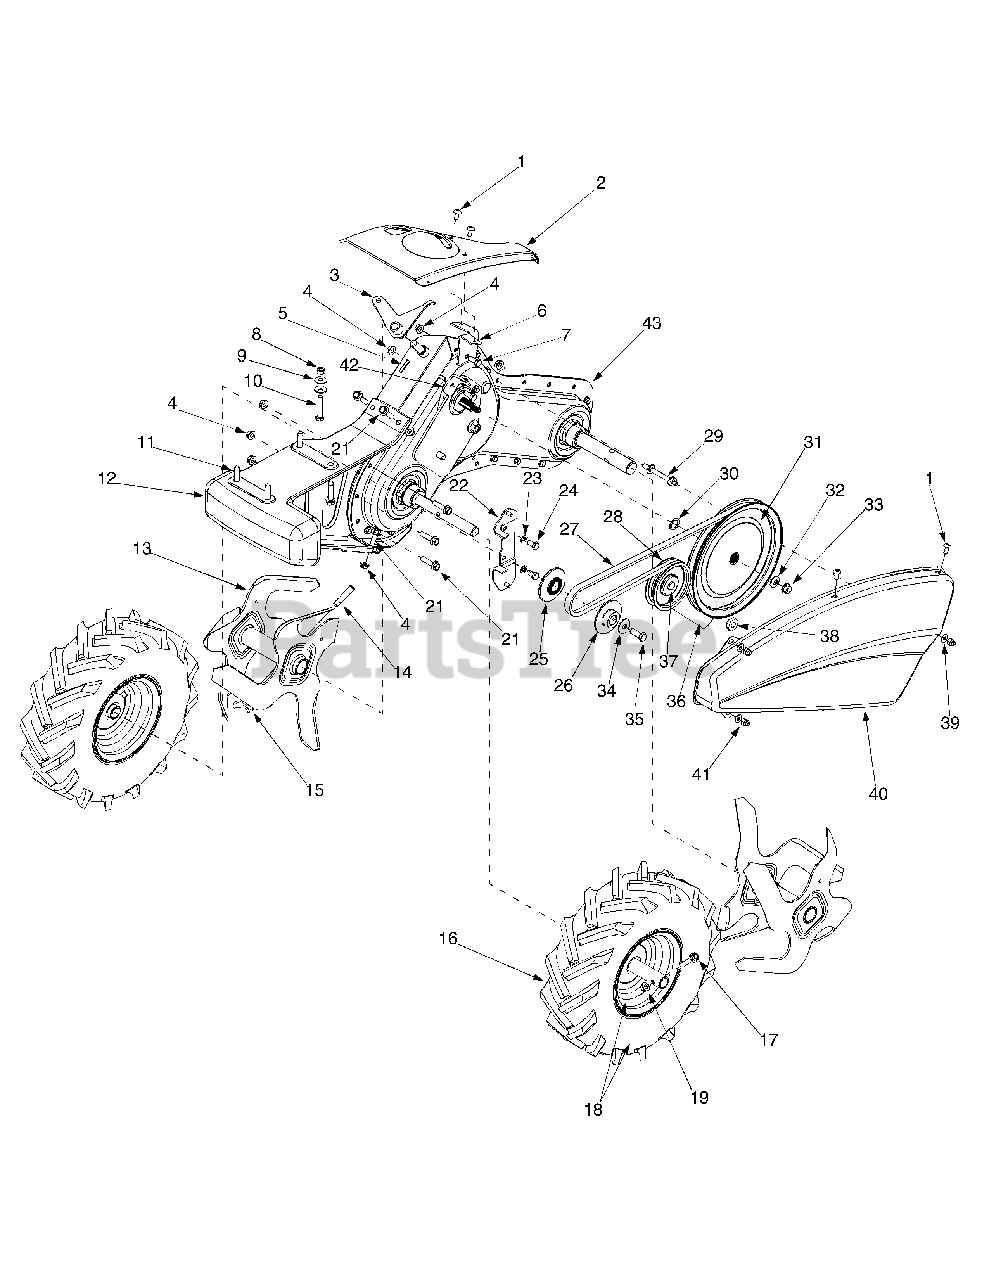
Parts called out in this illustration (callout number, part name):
1	Hex Screw 1/4-20 x.625
5	Spiral Pin
8	Hex Nut 5/16-18
9	Bell Washer.340 ID x.872 OD
10	Hex Cap Screw 5/16-18 x 1.75
11	Hex Washer Screw 3/8-16 x 1.5
12	Frame Counterweight
14	Clevis Pin
15	Cotter Pin
16	Complete Wheel Ass’y - RH (14")
17	Hex Head Screw 1/4-20
18	Rim Only (6.0 x 3.25)
19	Flange Lock Nut 1/4-20
21	Flange Screw 5/16-18 x 1.25
24	Hex Cap Screw 5/16-24 x.625
25	Inner Pulley Half
26	Outer Pulley Half
27	V-Belt
28	Flat Idler
29	Bolt 5/16-18 x 1/4-28 x 2.35
30	Flat Washer.635 ID x.930 OD
31	Flat Pulley
32	Spring Washer.401 ID x.870 OD
33	Flange Lock Nut 3/8-24
34	Bell Washer.396 ID x 1.140 OD
35	Hex Cap Screw 3/8-24 x 1.0
37	Hex Cap Screw 3/8-16 x 1.25
38	Shoulder Nut 7/16-20
39	Flat Washer.271 ID x.630 OD
42	Cable Bracket
43	Gear Case Assembly
